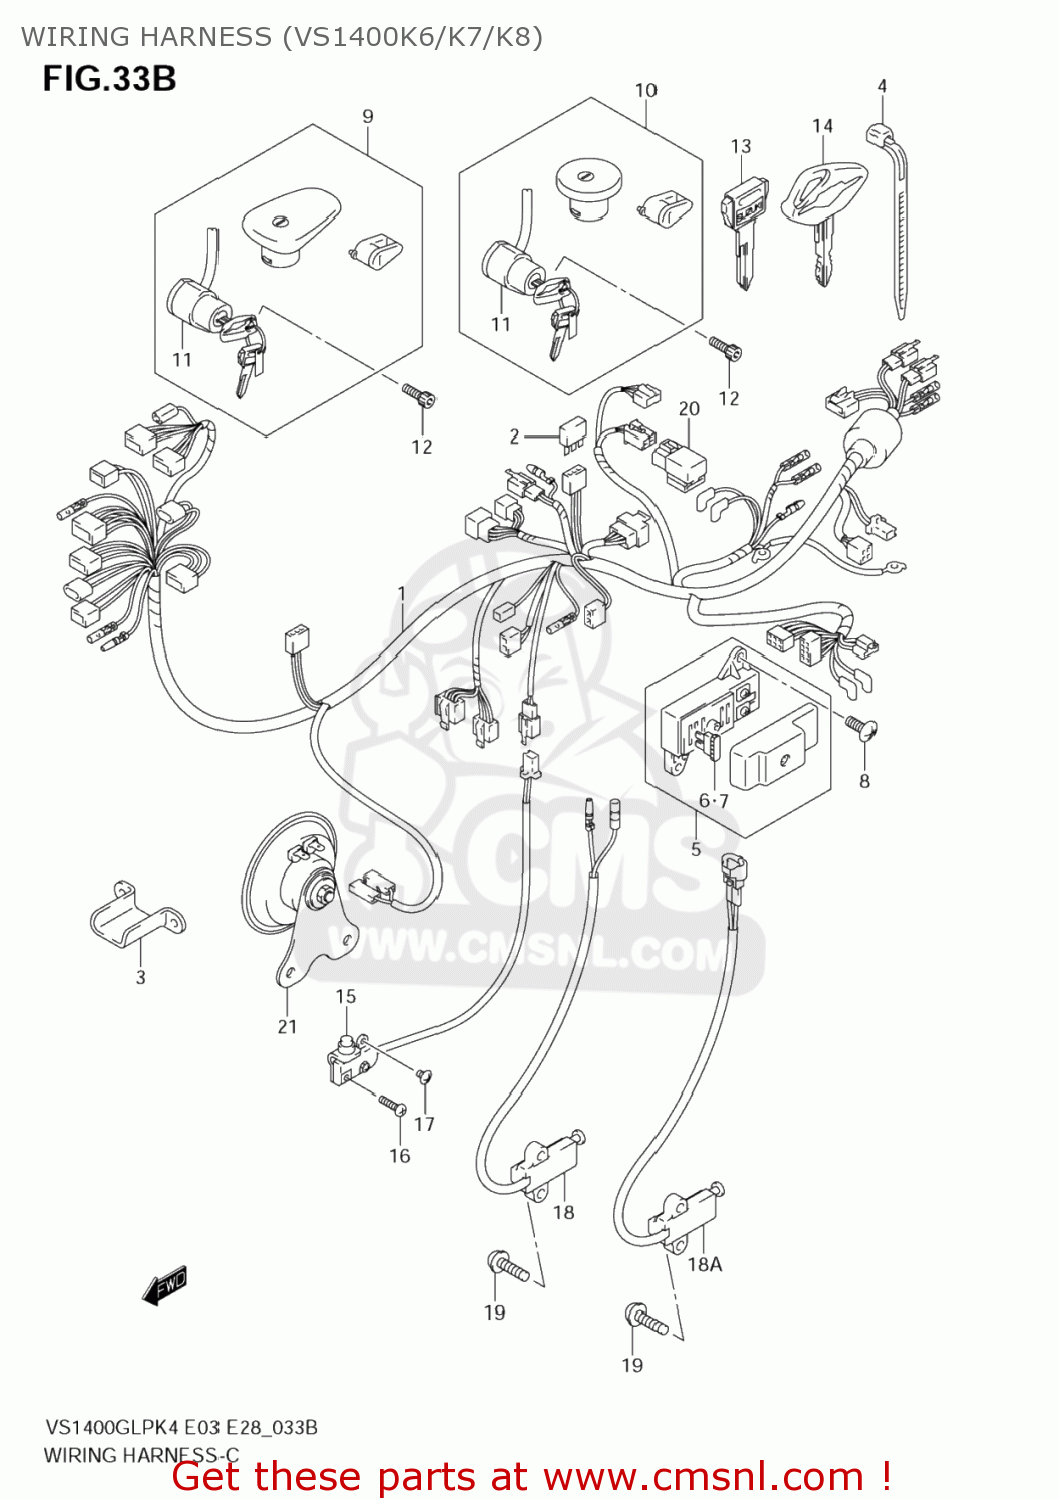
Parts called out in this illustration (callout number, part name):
1	HARNESS,WIRING
2	DIODE(STANLEY DE8804)
3	GUIDE,WIRING HARNESS
4	CLAMP(L:95)
5	BOX ASSY,FUSE
6	FUSE (25A)
7	FUSE(10A)
8	SCREW
9	LOCK SET
10	LOCK SET
11	SWITCH ASSY,IGNITION
12	BOLT
13	KEY,BLANK(TYPE:C)
14	KEY,BLANK(TYPE:C)
15	SWITCH ASSY,STOP LAMP
16	SCREW
17	SCREW
18	SWITCH ASSY,SIDE STAND
18A	SWITCH ASSY,SIDE STAND
19	SCREW
20	RELAY ASSY
21	HORN ASSY
